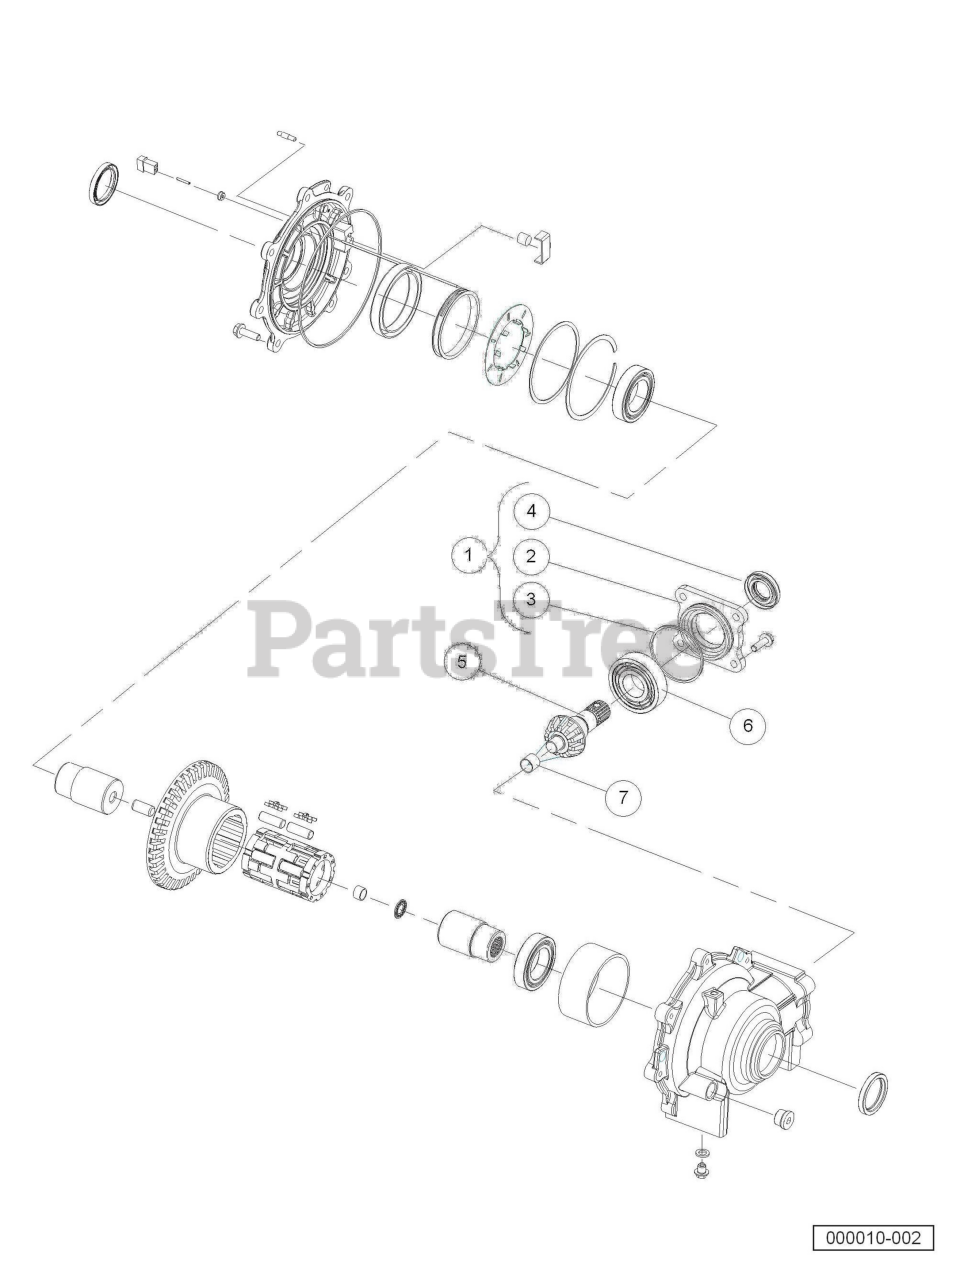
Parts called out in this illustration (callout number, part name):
1	Kit, Assy, Input Cover Plate
2	Cover, Input, Machined
3	O-Ring
4	Oil Seal, Triple-Lipped
5	Shaft, Pinion, Machined
6	Bearing, Ball
7	Bushing, Plain 16 Id X 15 Wide
